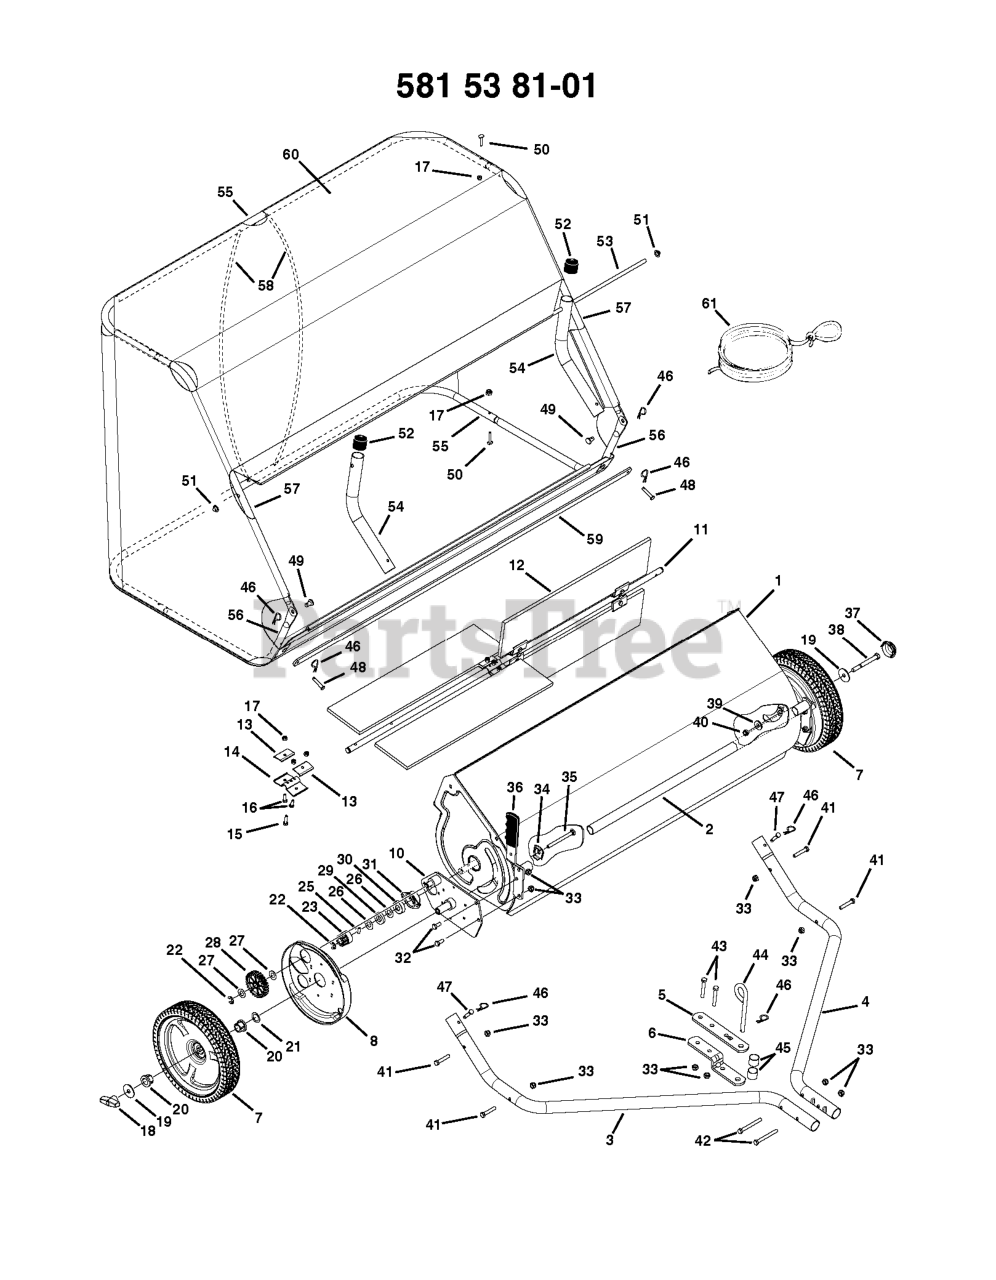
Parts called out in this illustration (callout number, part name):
1	HOUSING ASSY
6	Bracket, Hitch
8	DUST COVER
9	BRACKET
10	BRACKET
13	BRUSH RETAINER SINGLE
14	BRUSHRETAINER DOUBLE
18	Knob, Wing 5/16-18 Thread
21	Washer, Flat 1-1/8" x .78" x .025"
23	PINION
24	PINION
27	Washer, 1/2" x 1" x .02"
30	BALL BEARING
36	Rubber Grip
38	HEX BOLT
41	SCREW
42	Bolt, Hex 5/16-18 x 3" Lg.
44	Pin, Hitch
46	Pin, Hair Cotter 3/32" #3
54	TUBE.BAG.ARM.AGRI-FAB
58	HOPPER SUPPORT ROD
59	STRAP BAG FRAME
60	ASS'Y HOPPER BAG (22 CU. FT)
